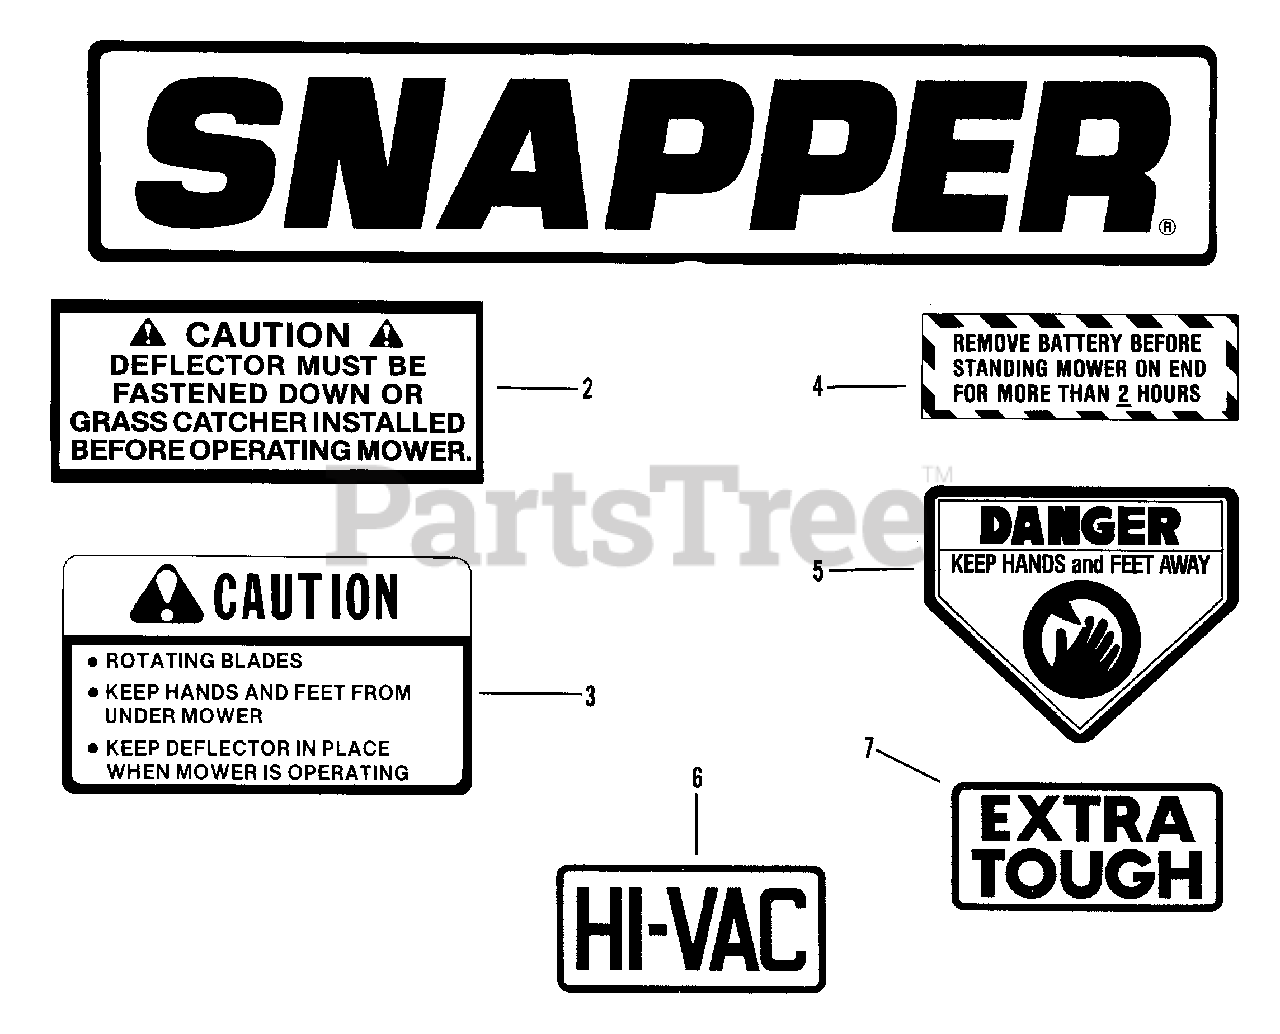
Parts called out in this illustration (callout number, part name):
2	DECAL, Caution - Deflector
3	DECAL, Caution - Rotating Blades
4	DECAL, Battery
5	DECAL, Danger (Cut Finger)
6	DECAL, Hi-Vac
7	DECAL, Extra Tough
